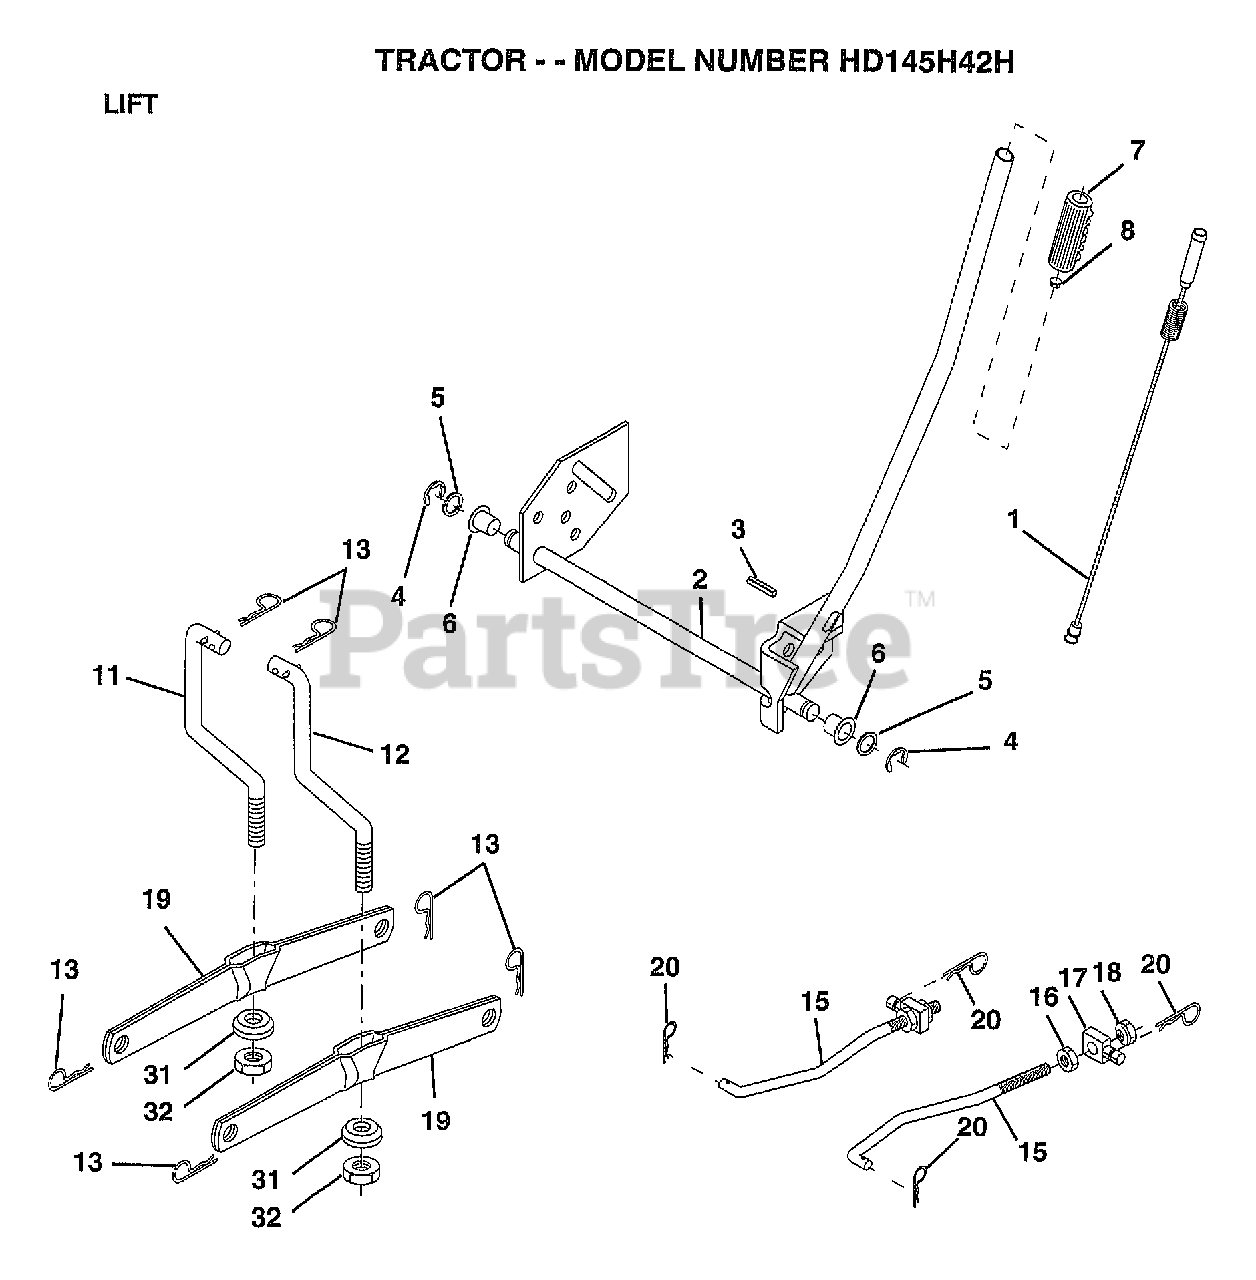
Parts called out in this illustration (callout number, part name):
1	WIRE ASM W.SPRING
2	"SHAFT ASM LIFT,RH"
3	PIN-GROOVE LT
5	WASHER
6	NYLON BEARING
7	GRIP
15	LINK.FRONT
16	NUT
17	TRUNION
18	NUT.LK.W/WSH.1/2.
19	ARM SUSP REAR
20	RETAINER.SPRING
31	BEARING PVT LH
32	NUT.CROWNLOCK.3/8
